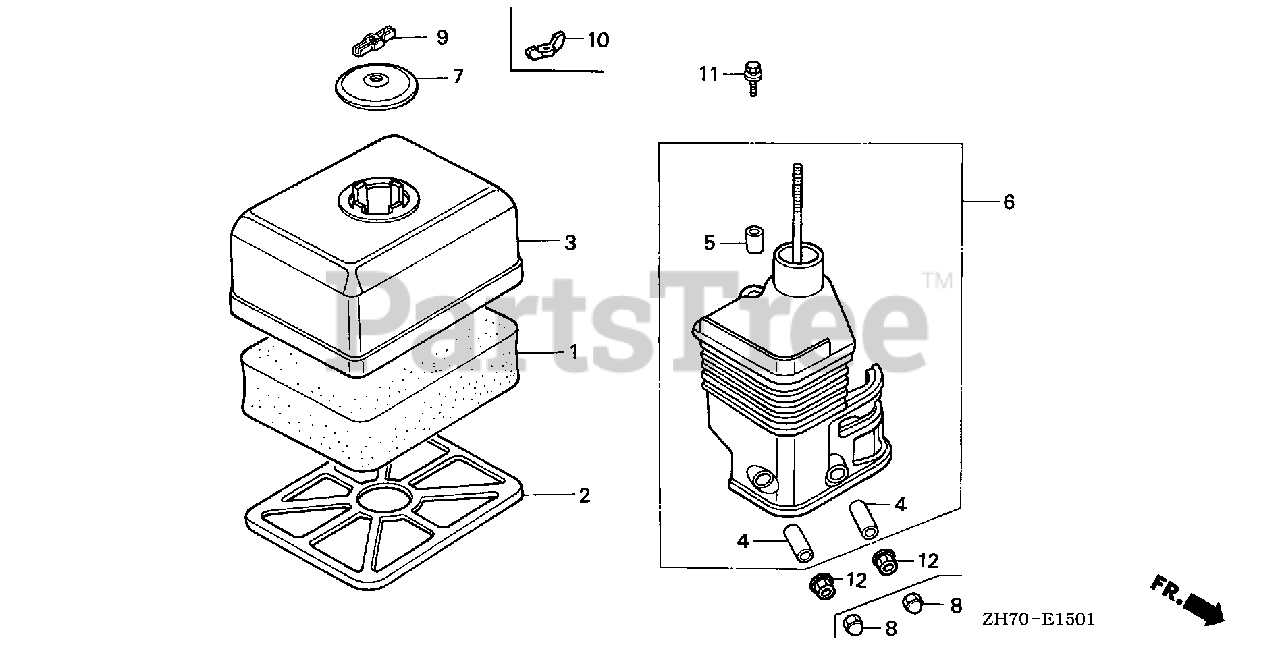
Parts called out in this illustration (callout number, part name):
1	ELEMENT, AIR CLEANER (SEMI-DRY)
2	GRID, AIR CLEANER (SEMI-DRY)
3	COVER, AIR CLEANER (SEMI-DRY)
4	COLLAR, AIR CLEANER
5	COLLAR B, AIR CLEANER
6	ELBOW, AIR CLEANER
7	CAP, CLEANER
8	NUT, CAP (6MM)
9	NUT, AIR CLEANER COVER (DACRO COATING)
9	WINGNUT (6MM) (BLACK)
10	NUT, TOOL BOX SETTING
11	BOLT-WASHER (6X20)
12	NUT, FLANGE (6MM)
